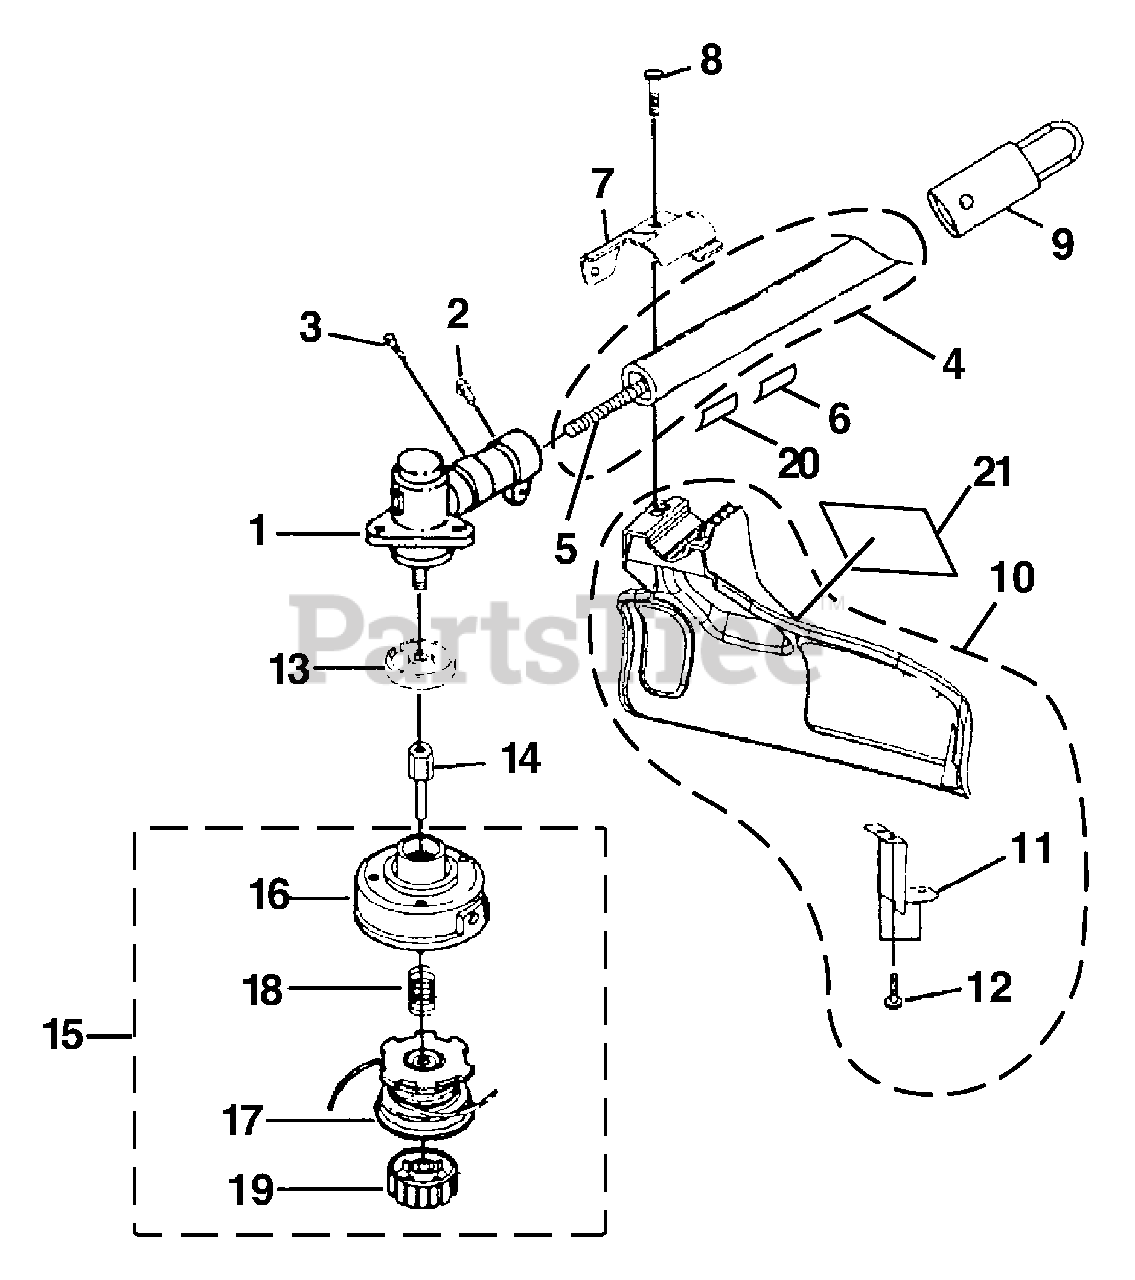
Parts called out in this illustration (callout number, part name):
1	GEAR HEAD ASSEMBLY W/SCREWS
2	SCREW (10-24 X 5/8 in. HEX HD.)
3	CAP SCREW (1/4-20 X 1-1/4 in.)
4	DRIVE SHAFT HOUSING ASSEMBLY
5	FLEXIBLE SHAFT ASSEMBLY
6	WARNING DECAL
7	GRASS SHIELD CLAMP
8	SCREW (1/4-20 X 1-1/4 in. PAN HD.)
9	HANGER CAP
10	GRASS SHIELD ASSEMBLY W/SCREWS
11	CUT-OFF BLADE
12	SCREW (8-16 x 1/2 in. PAN HD.)
13	FLANGE WASHER
14	STRING HEAD ADAPTER
15	STRING HEAD ASSEMBLY
16	HOUSING W/EYELET
17	SPOOL W/STRING
18	COMPRESSION SPRING
19	SPOOL RETAINER
20	WARNING LABEL
21	LOGO PLATE
